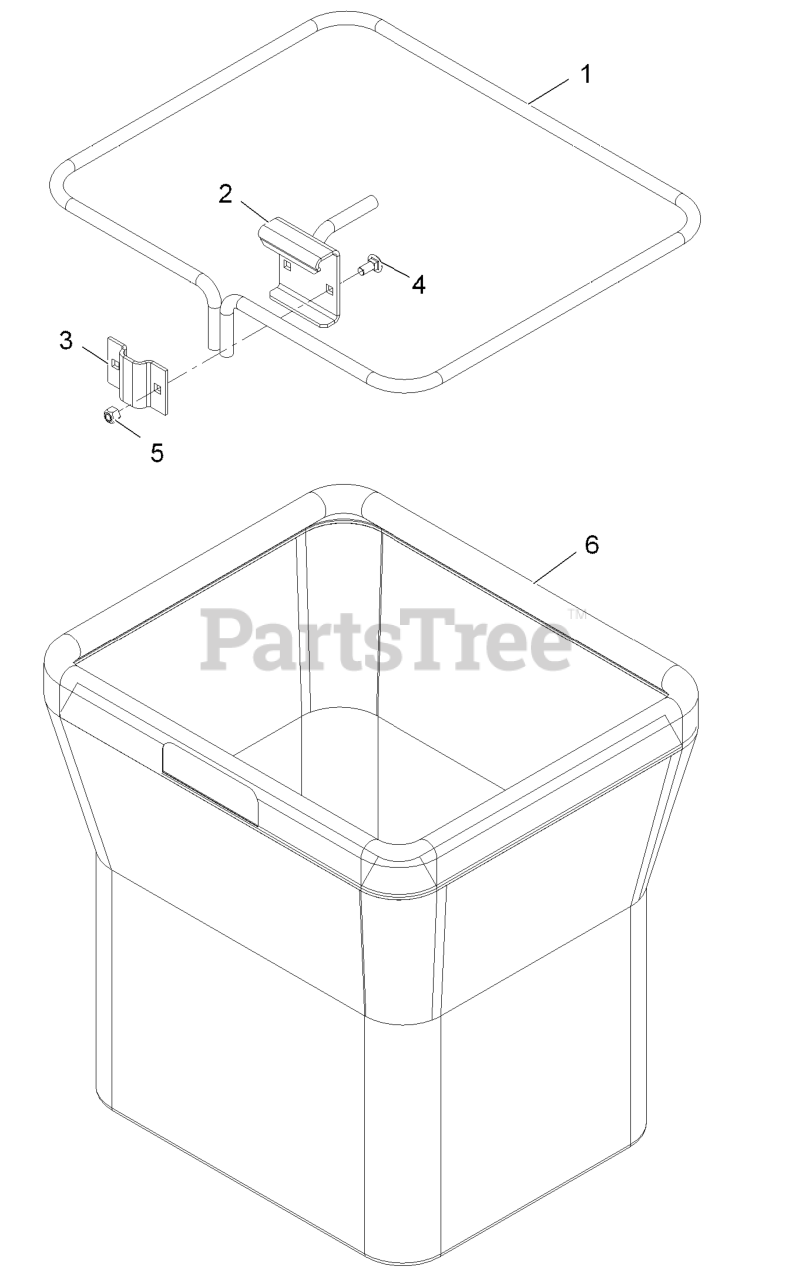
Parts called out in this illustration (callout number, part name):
1	FRAME-BAG
4	BOLT-CARR
5	NUT-LOCK, NI
6	BAG,20 IN. DEPTH
